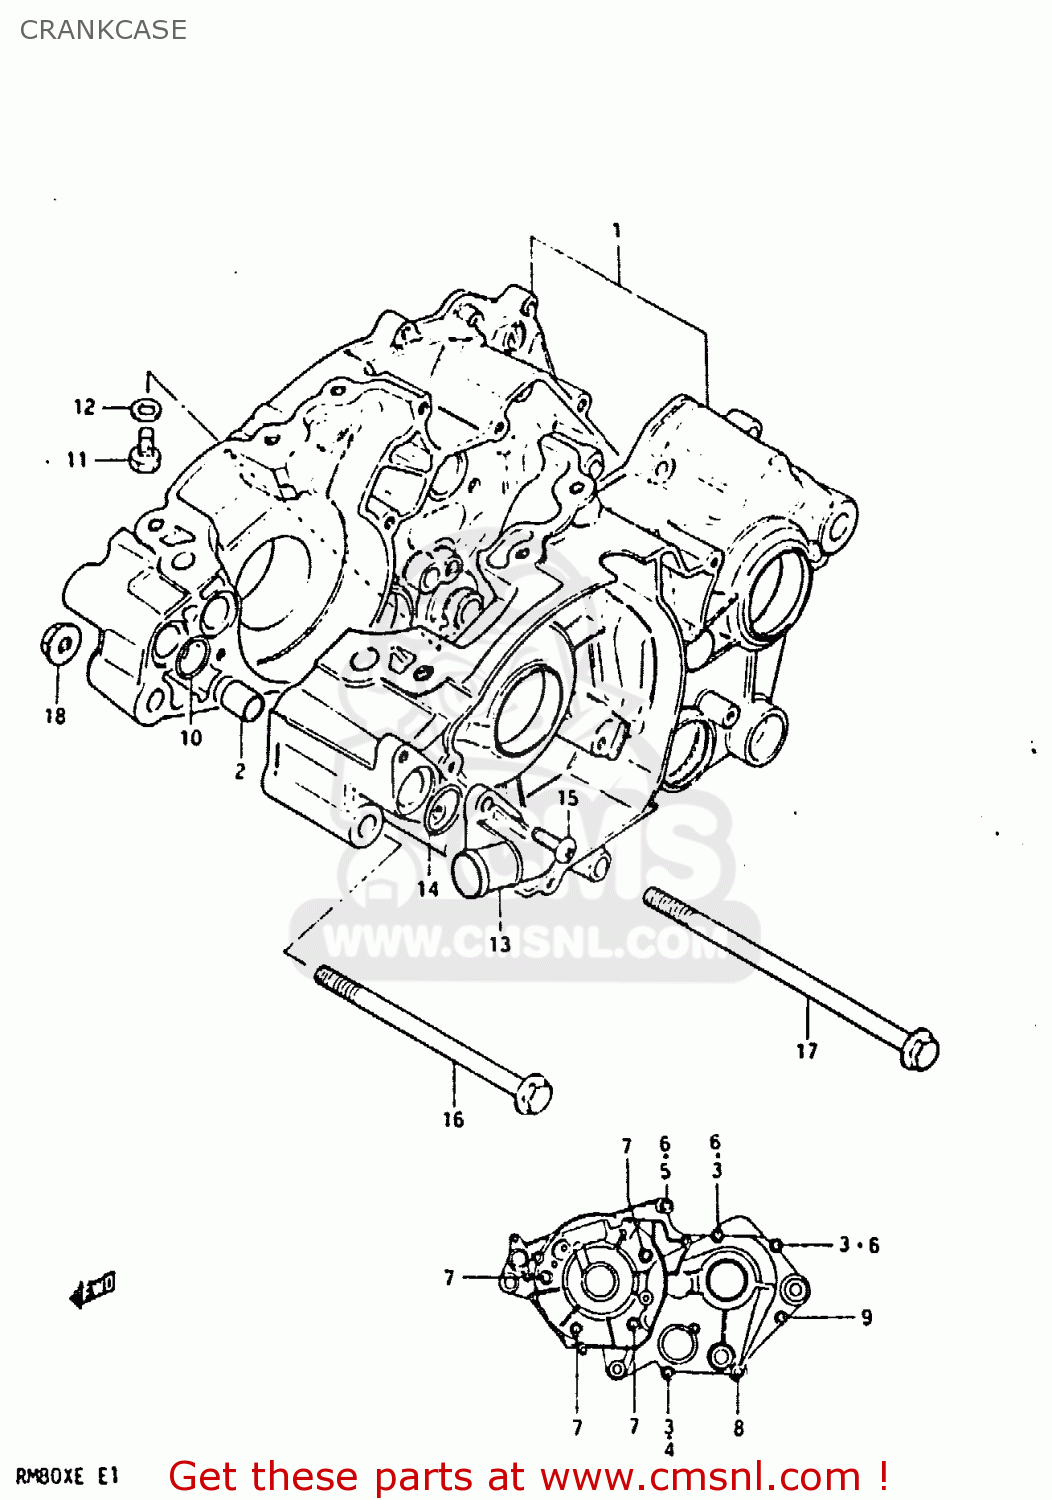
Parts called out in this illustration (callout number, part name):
1	CRANKCASE SET
2	PIN
3	SCREW
4	SCREW
5	SCREW (6X35)
6	SCREW (6X35)
7	SCREW
8	SCREW (6X45)
9	SCREW
10	O-RING,BOSS
11	BOLT
12	GASKET 8.2X14X1 (NAS)
13	CONNECTOR,WATER HOSE
14	O-RING,BOSS
15	SCREW
16	BOLT(8X95)
17	BOLT(8X125)
18	NUT
